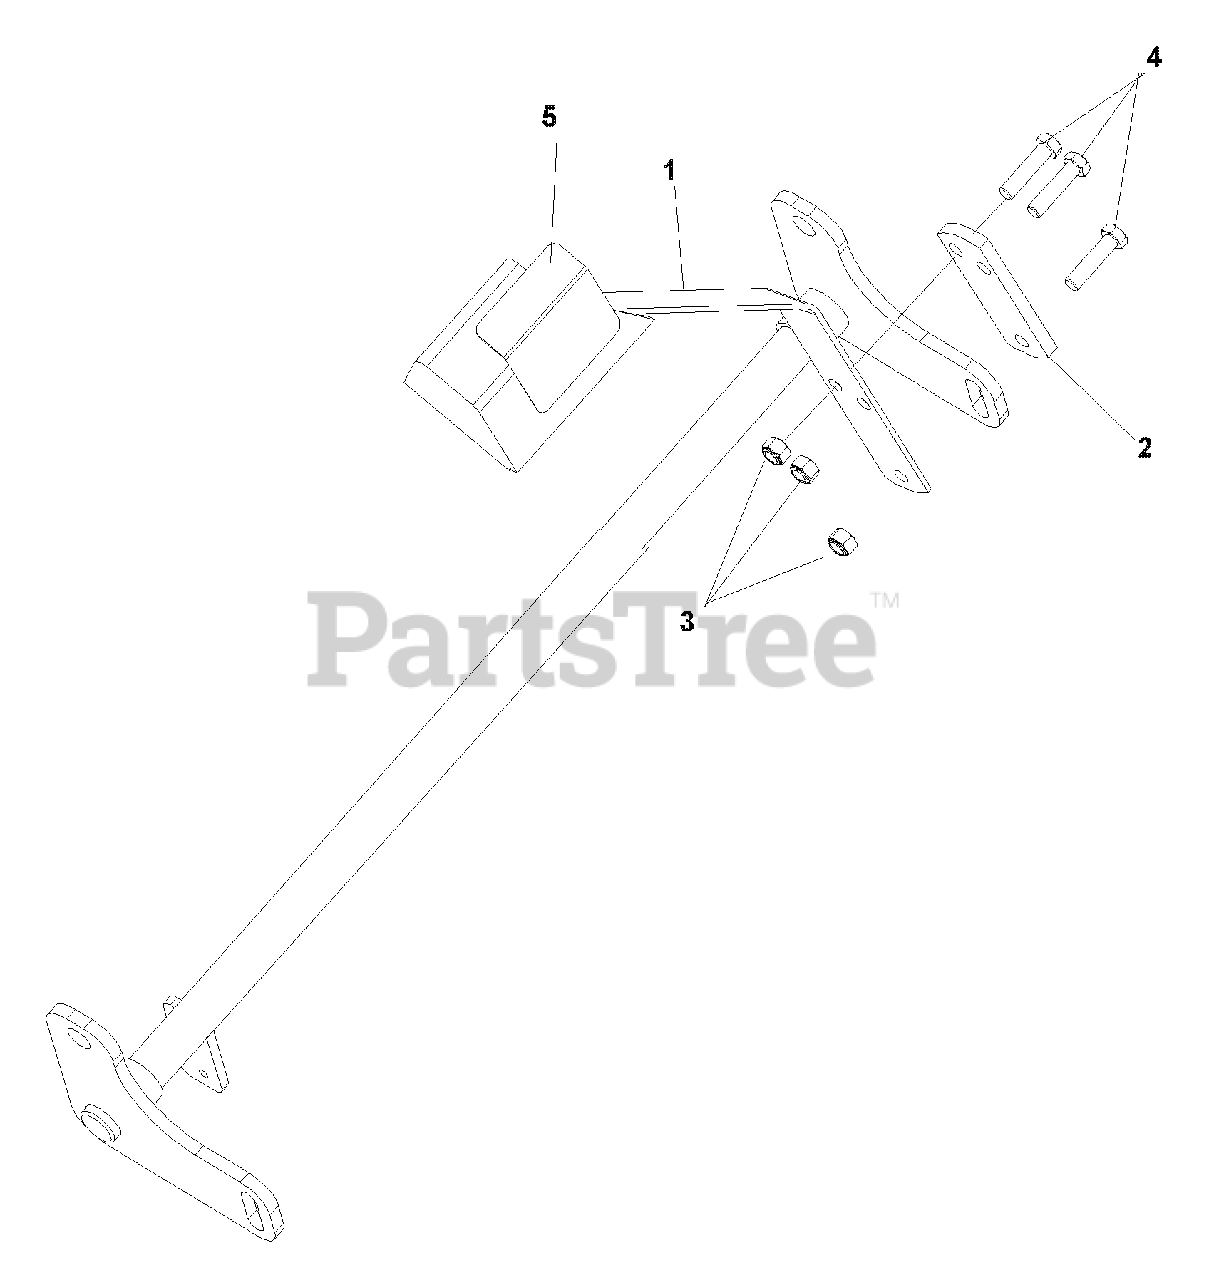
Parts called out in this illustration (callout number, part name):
1	Lift Pedal W/pad
2	Tightening Plate
3	Nut 3/8C Nyloc
4	HCS 3/8C X 1 1/2
5	Pad, non-skid
